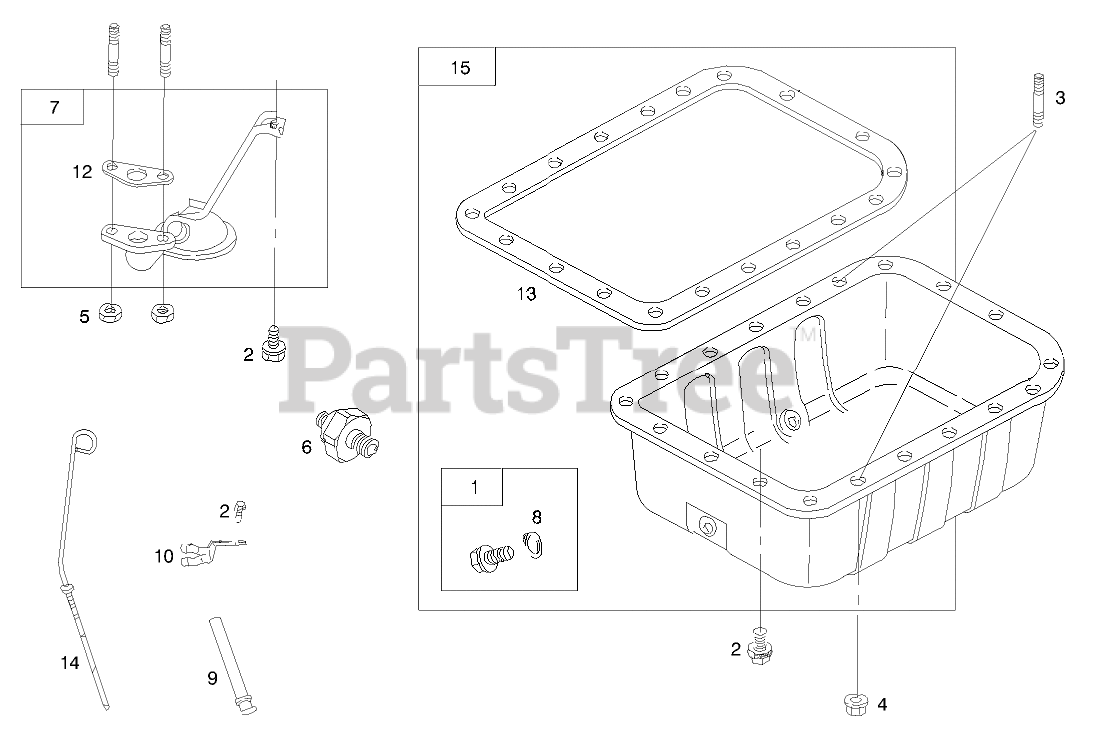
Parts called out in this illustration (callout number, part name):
1	PLUG-OIL DRAIN (12MM)
1	HEAD-CYLINDER
2	SCREW-HEX
3	STUD-METRIC
4	NUT-HEX, METRIC
5	NUT-HEX, METRIC
6	SWITCH-PRESSURE, OIL
7	SCREEN-PUMP, OIL
8	WASHER-SEAL (12MM)
8	SWITCH-TEMPERATURE, WATER
9	TUBE-DIPSTICK
9	GASKET-SET
10	BRACKET-SUPPORT
12	GASKET-STRAINER, OIL
13	GASKET-PAN, OIL
14	Dipstick
14	KIT-VALVE OVERHAUL
15	PAN-OIL
15	SHAFT-GEAR
